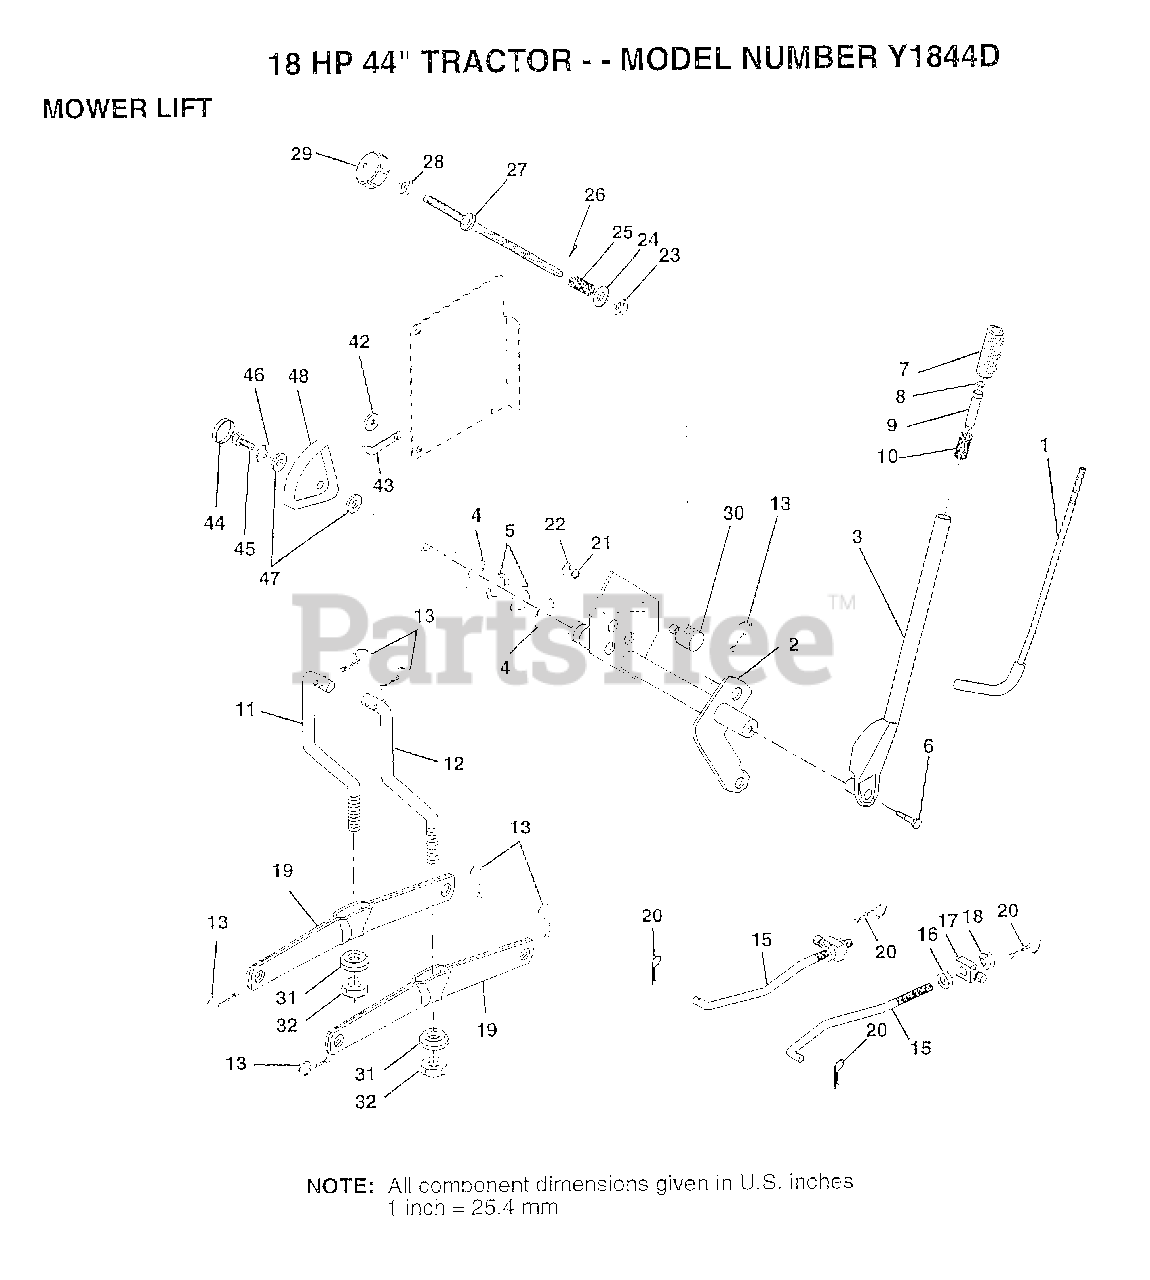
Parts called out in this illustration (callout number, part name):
1	LEVER ROD LT
2	SHAFT LIFT W/IND
4	E-RING
5	WASHER
6	"BOLT,HEX"
7	GRIP
10	SPRING T
11	LINK LIFT LH
12	LINK LIFT RH
15	LINK.FRONT
16	NUT
17	TRUNION
18	NUT.LK.W/WSH.1/2.
19	ARM SUSP REAR
20	RETAINER.SPRING
21	WASHER
22	KLIP RING
23	NUT T
24	WASHER
25	SPRING T
27	ROD LIFT LT
28	NUT
29	KNOB INF 3/8-16
30	TRUNION LT
31	BEARING PVT LH
32	NUT.LOCK.3/8-24
42	WASHER T
43	POINTER HGT IND
44	"PLUG,HOLE"
46	LOCKWASHER
47	WASHER
48	HEIGHT INDICATOR
